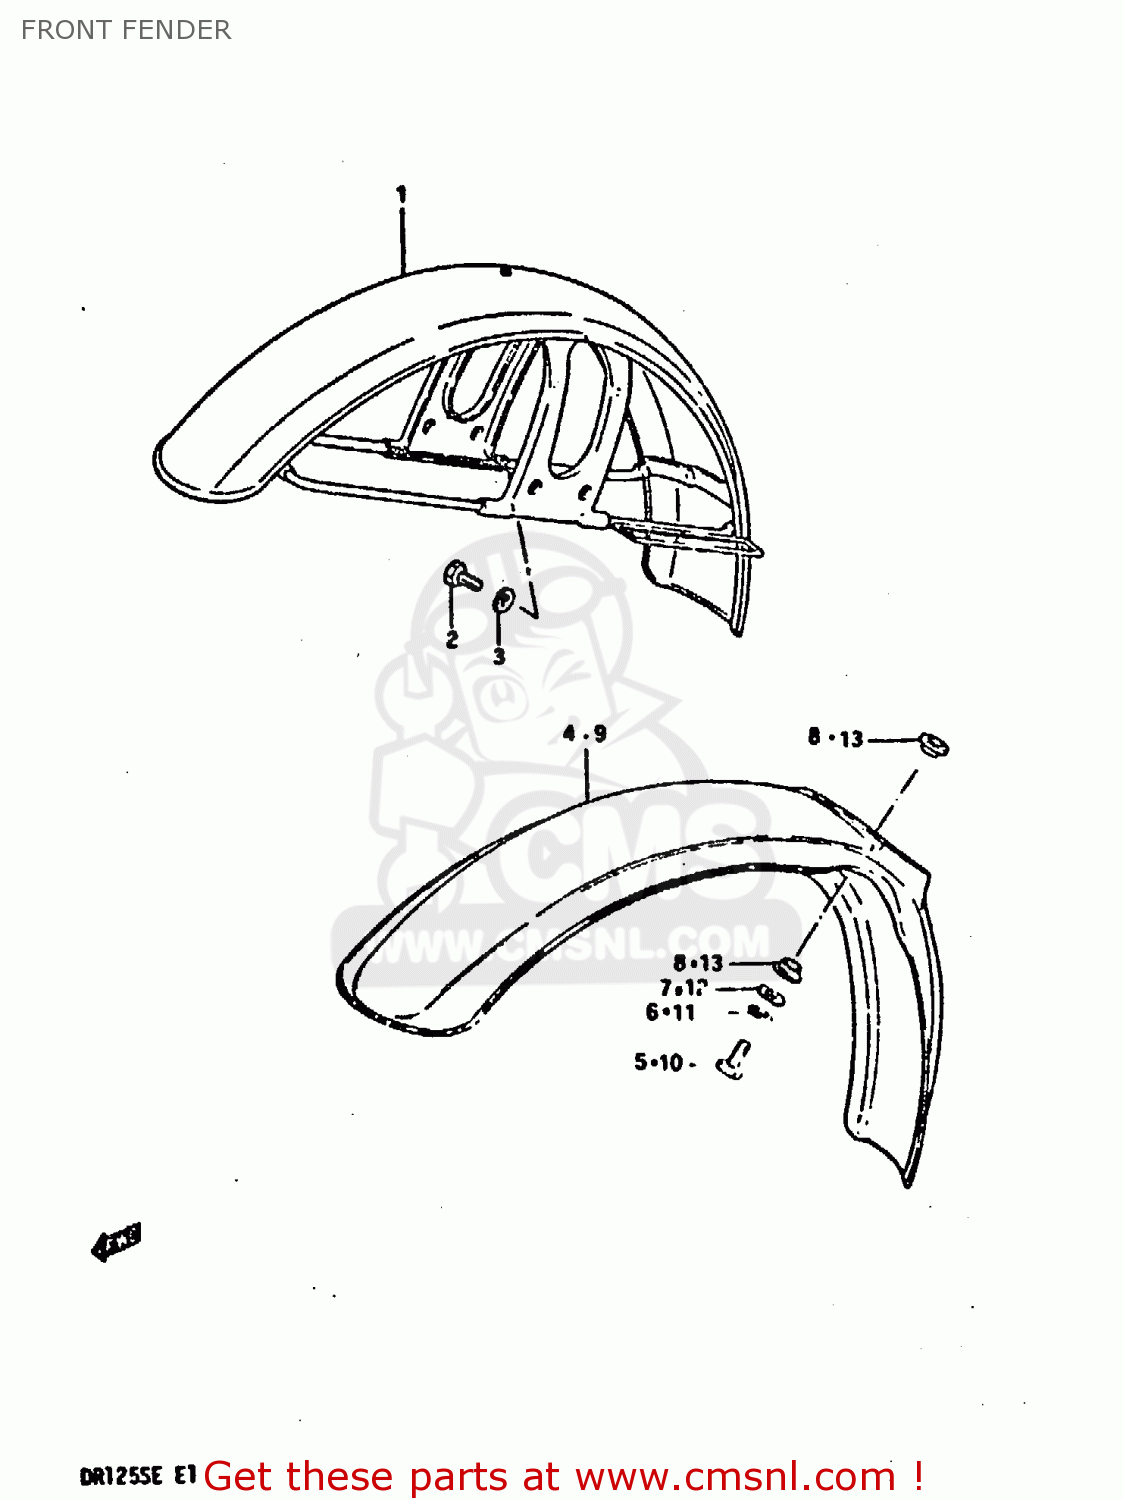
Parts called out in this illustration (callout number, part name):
1	FENDER,FR
2	BOLT, FRONT FENDEER FRONT
3	LOCK WASHER
4	FENDER,FR
5	BOLT, UPPER
6	LOCK WASHER
7	WASHER
8	SPACER
9	FENDER,FRONT
10	BOLT, UPPER
11	LOCK WASHER
12	WASHER
13	SPACER
